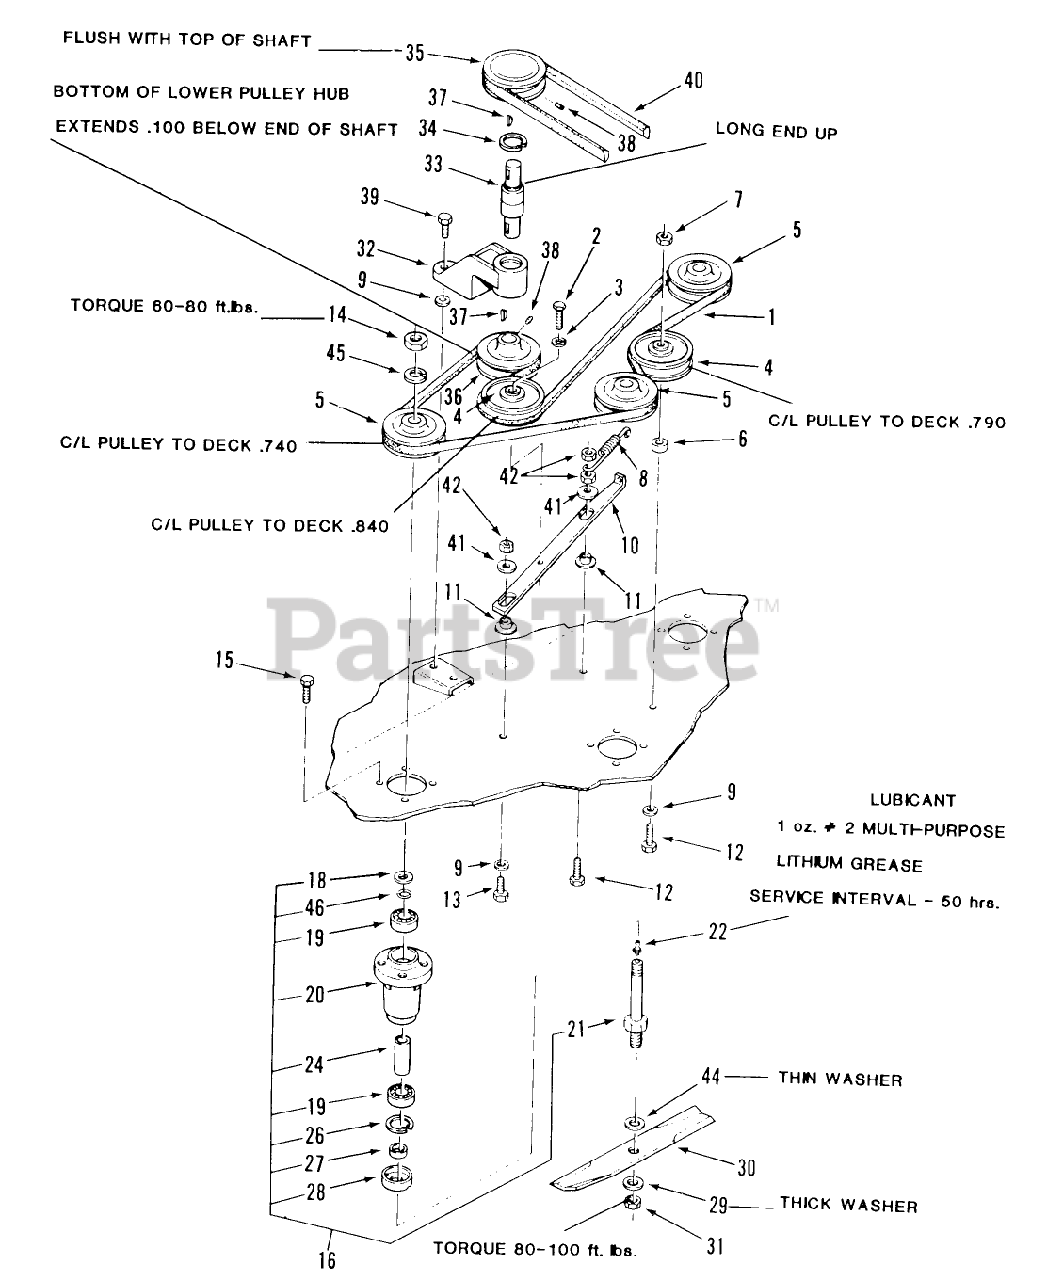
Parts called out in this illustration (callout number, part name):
1	V BELT
5	PULLEY
8	SPRING-EXTENSION
9	WASHER
11	SPACER-BUSHING
19	BEARING-BALL
20	HOUSING-SPINDLE
26	Ring-Snap
27	SPACER-BLADE
29	SpeciaI Washer
30	S/A BLADE KIT
35	PULLEY
37	KEY-WOODRUFF
39	Bolt
40	V-BELT
41	WASHER
46	O RING
